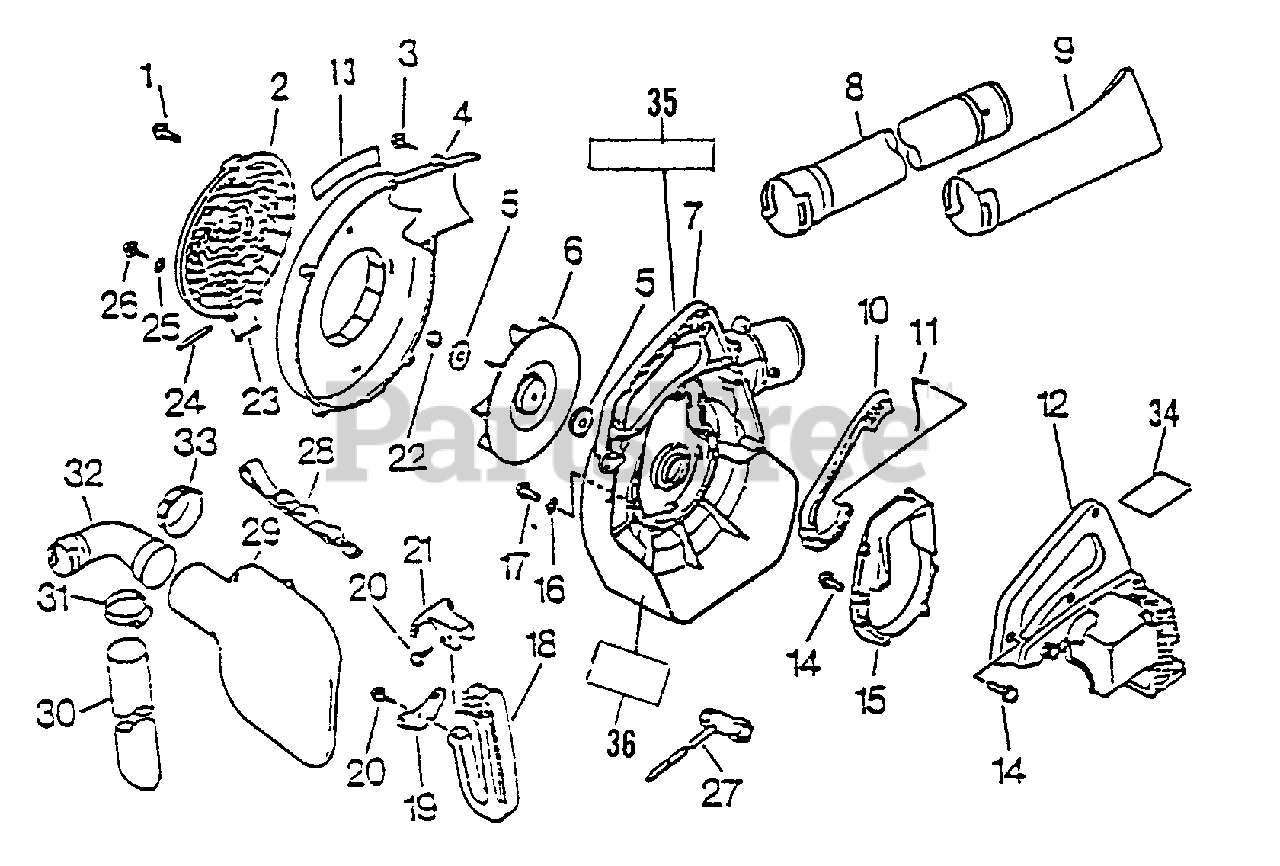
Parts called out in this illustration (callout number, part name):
1	THUMBSCREW
2	GUARD, DEBRIS
3	SCREW - 5X20 -- TAPPING
4	COVER, FAN - LEFT
5	WASHER - 8
6	FAN
7	COVER, FAN - RIGHT
8	TUBE, BLOWER - STRAIGHT
9	NOZZLE - FAN HEAD
10	TRIGGER, THROTTLE
11	ROD, THROTTLE
12	COVER, ENGINE
13	LABEL - MODEL
14	SCREW - 4X18
15	BRACKET, ENGINE
17	SCREW - 4X22
18	HANDLE - REAR
19	BRACKET, HANDLE - LOWER
20	SCREW - 5X14
21	BRACKET, HANDLE - UPPER
26	SCREW - 5X14
27	T-WRENCH - 13X19mm
28	SHOULDER STRAP ASSY
29	BAG, DEBRIS
30	TUBE, VACUUM
32	TUBE, DEBRIS
34	LABEL - HOT SURFACE
35	LABEL - NOISE
36	LABEL - CAUTION
